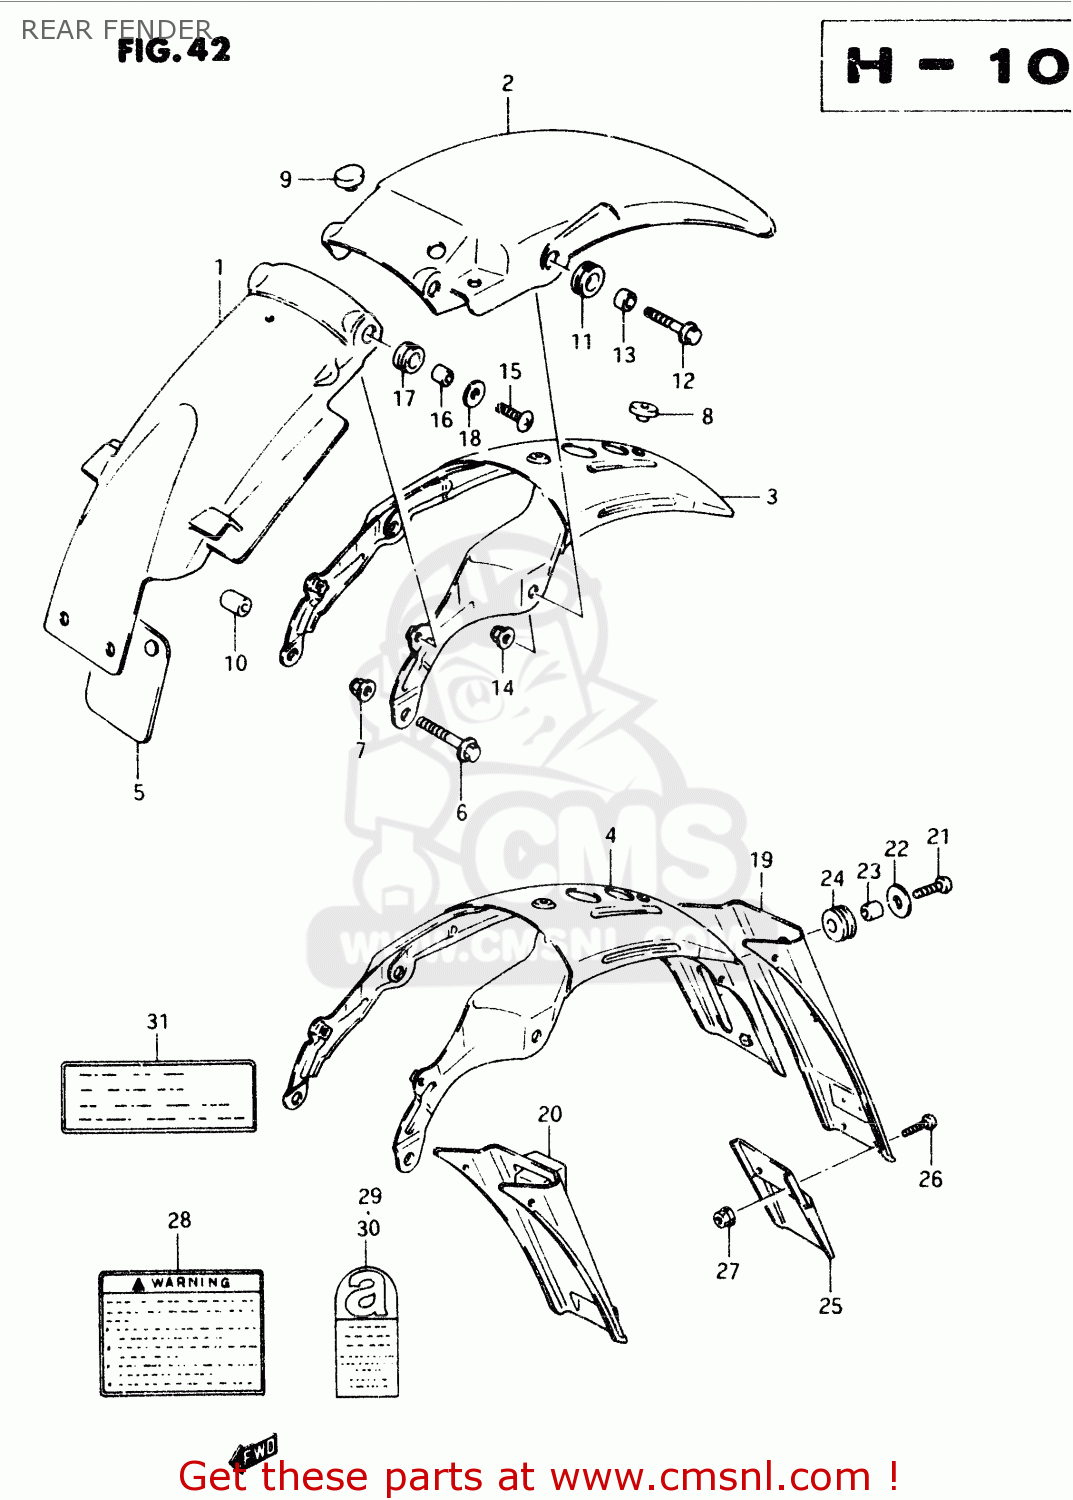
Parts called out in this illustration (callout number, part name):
1	FENDER, RR FR
2	FENDER,RR
3	REINFORCEMENT,RR FENDER
4	REINF,RR FENDER
5	GUARD,RR FENDER FR MUD
6	BOLT
7	NUT
8	CUSHION
9	CUSHION
10	CUSHION
11	CUSHION
12	BOLT
13	SPACER (8.2X12X7.5)
14	NUT
15	SCREW
16	SPACER (6.8X10X10)
17	CUSHION
18	WASHER
19	EXTENSION, REAR FENDER
20	EXTENSION,RR FENDER
21	SCREW
22	WASHER (6.5X22X1.6)
23	SPACER(6.2X8.3X6.1)
24	CUSHION
25	EXTENSION, REAR FENDER
26	SCREW, FRONT & REAR
27	NUT
28	LABEL, WARNING
29	LABEL,ASBESTOS WARNING
30	LABEL, WARNING ASBESTOS (GERMAN)
31	LABEL,CAUTION
32	MANUAL, OWNER'S
33	LABEL, TIRE AIR PRESSURE
